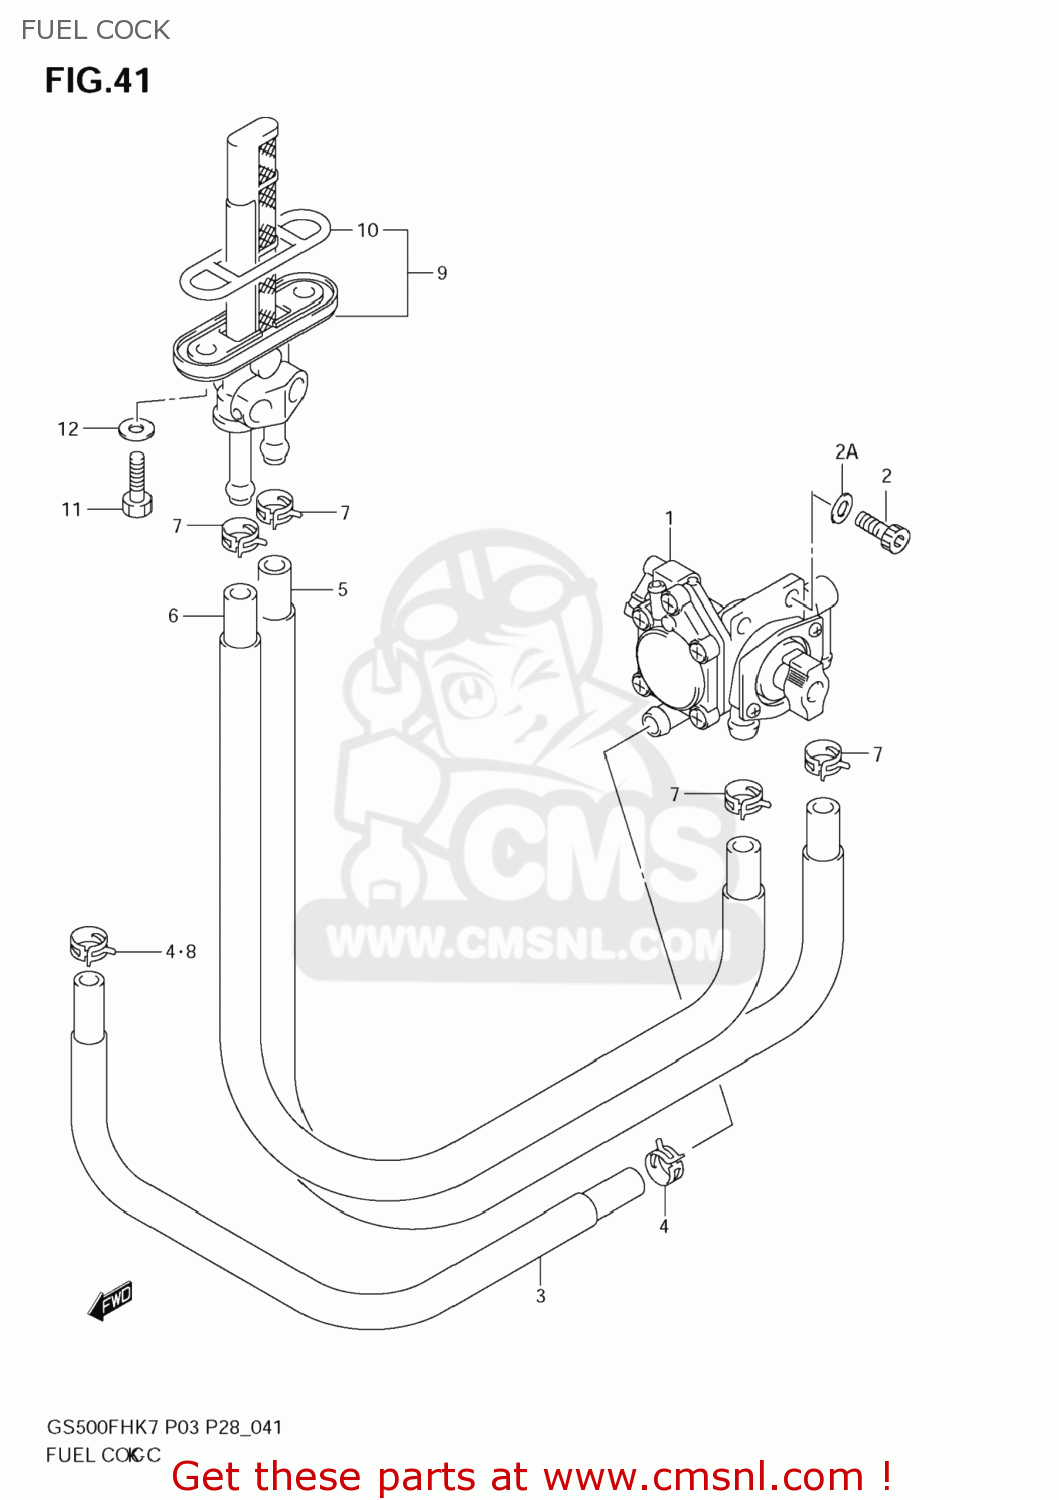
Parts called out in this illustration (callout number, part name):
1	COCK ASSY, FUEL
2	BOLT 6X12 UH20
2A	WASHER GS500/K
3	HOSE,FUEL
4	CLIP
5	HOSE, FUEL "RES"
6	HOSE,FUEL ON
7	CLIP
8	CLIP
9	COCK ASSY,FUEL NO.1
10	O RING,FUEL COCK
11	BOLT(6X20)
12	GASKET(6.4X11.5X0.8) (NAS)
